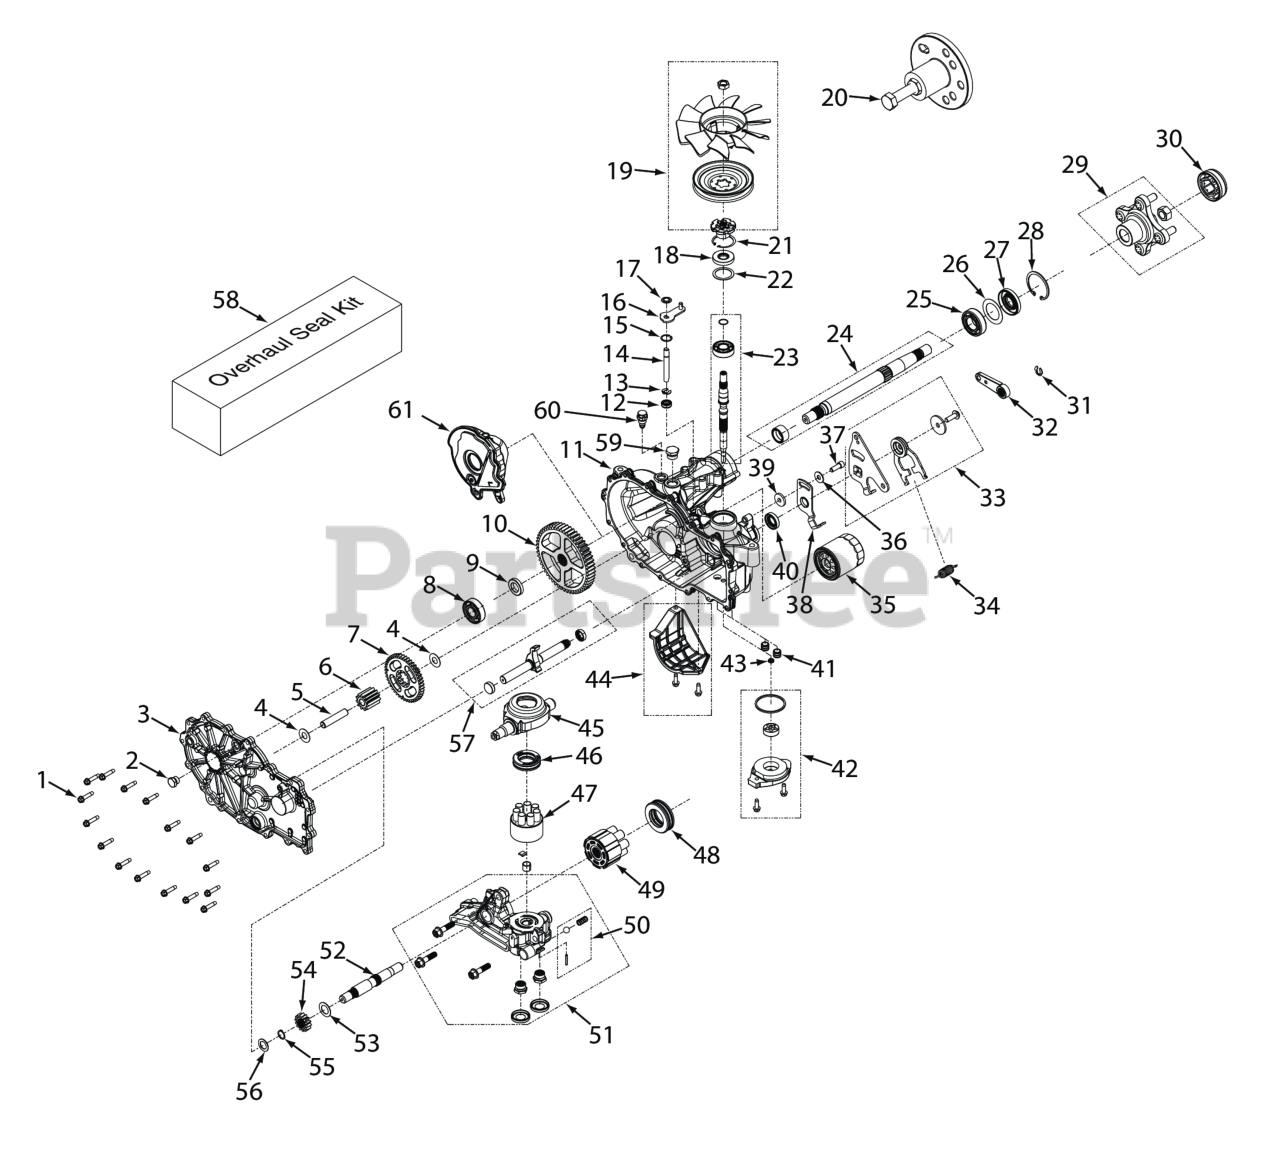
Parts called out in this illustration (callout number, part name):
1	Bolt, Hex Head 1/4-20 x 1-1/8"
2	Plug, External Hex Vent 9/16-18
3	Kit, Side Cover LH
4	Washer, .5 x 1.0 x .03
5	Jackshaft Pin
6	Gear, 11T
7	Gear, 45T
8	Kit, Bearing
9	Spacer, .750 x 1.320 x .257
10	Gear, 54T
11	Kit, Main Housing LH, Charge, Control
12	Seal, Lip, .375 x .75 x .25
13	Ring, .Retaining .375 External
14	Rod, By-Pass
15	R i n g , Retaining .750 Internal
16	Arm, Bypass (LH)
17	Ring, Retainging .375 External
18	Seal, Lip 17 x 40 x 7
19	Kit, Fan/Pulley
20	Kit, Hub Puller
21	R i n g , Retaining 2.06 Internal
22	Washer, 1.23 x 1.56 x .04
23	Kit, Input Shaft
24	Kit, Shaft, Axle
25	Bearing, Ball 1.0 x 52 x 15 Open
26	Spacer, 1.355 x 2.035 x .021
27	Seal, Lip TC4 1.0 x 2.06 x .38
28	R i n g , Retaining 2.06 Internal
29	Hub, 4-Bolt
30	Cap, Axle
31	Ring, Retaining External .375"
32	Handle, Brake
33	Kit, RTN Bi-Directional (Right Side)
34	Spring, Extension, RTN - 44lbs
35	Filter, Oil
36	Washer, 7/16 x 7/8 OD x .06 HT
37	Bolt, Hex Head Cap Screw 5/16-24 x 1" Patch
38	Arm, Neutral (Left Side)
39	Spacer, .32 ID x 1.005 OD x .1495 Thk
40	Seal, Lip 18 x 32 x 7
41	Tube, Charge Triple O-ring
42	Kit, Charge Pump
43	Kit, Gerotor Seal
44	Kit, Filter Guard (LH)
45	Trunnion, Swashplate
46	Ball Thrust Bearing
47	Kit, Cylinder Block
48	Thrust Ball Bearing Assembly
49	Kit, 16cc Cylinder Block Assembly (steam
50	Kit, Charge Relief
51	Kit, Charge Relief
52	Shaft, Motor
53	Washer, .72 x 1.16 x .04
54	Washer, Flat, .71 x 1.16 x .04
55	Ring, Retaining .625
56	Washer, HT .62 ID x 1.0 OD x .05 Thick
57	Kit, Outboard, RH Rot B / LH Rot A (LH)
58	Kit, Seal (ZT-2800)
59	Plug, 3/4-16
60	Fitting 9 /16 - 18, Breather
61	Expansion Tank, Internal LH
